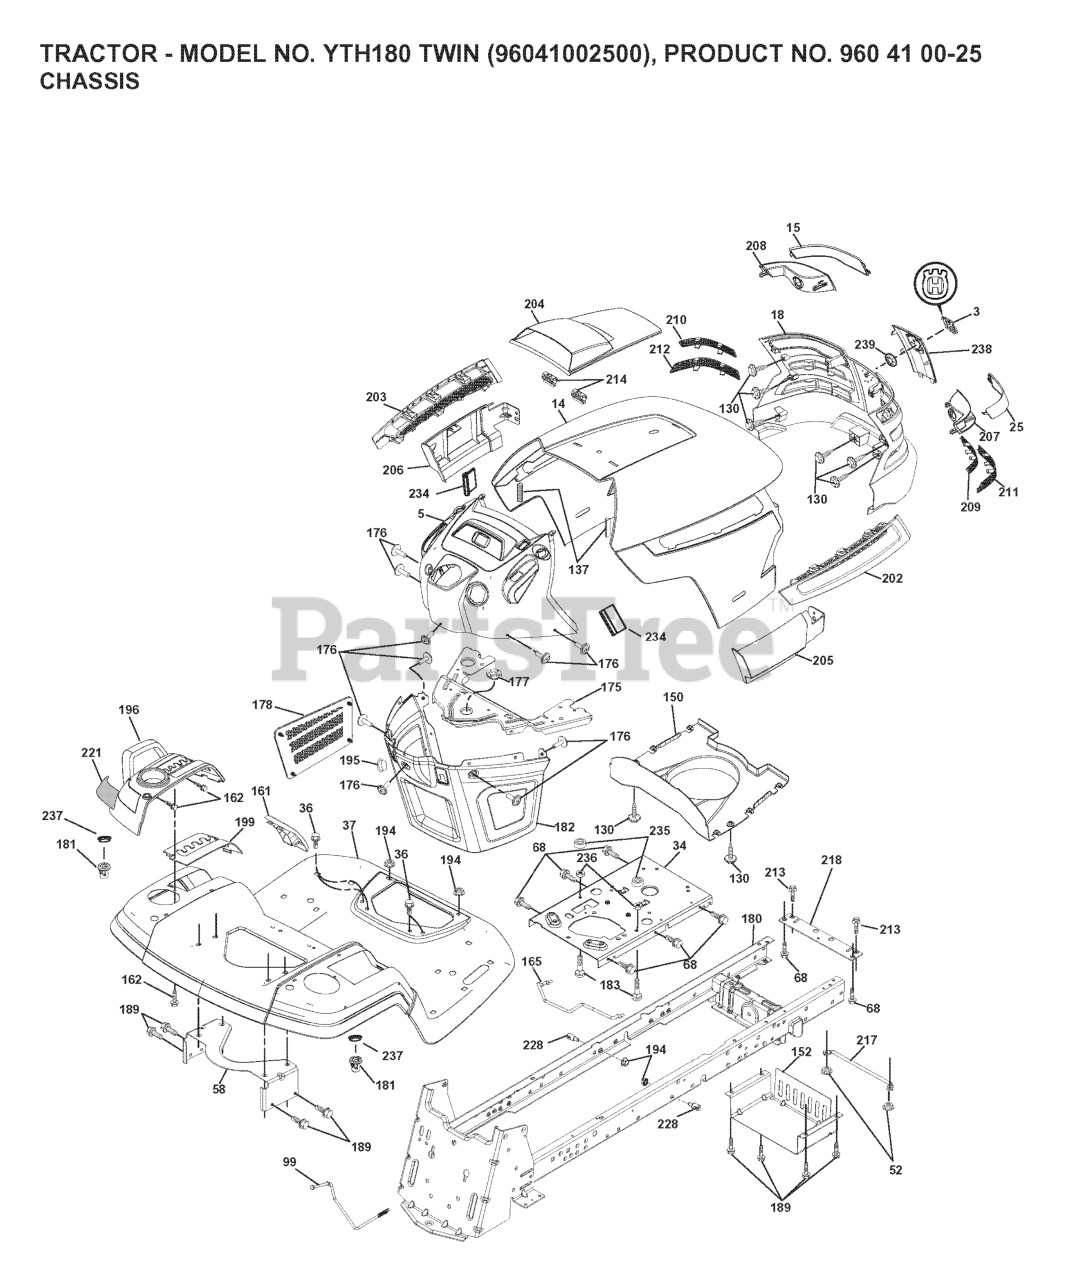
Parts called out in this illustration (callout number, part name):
3	RP LOGO
5	DASH.ASM.HUSQ.GT.E.RECT.W/CK
14	HOOD
15	LENS.LH.TEX.GT.HUSQ.CL
18	GRILL.ASM.HUSQ.TG/CRD.W/TRIM
25	LENS.RH.TEX.GT.HUSQ.CL
34	PLATE.ENGINE.WELDED.CHASSIS
36	SCREW 5/16"
37	FENDER.PNT.TX.GT.CH/FW.ORANGE
52	LOCKNUT
58	BRKT.SUPPORT.FNDR/TANK
68	Screw 5/16-18 x 1/2 Hex, Self Tapping 5/16-18 x 1/2
99	ROD ASM BYPASS
130	SCREW
137	BUMPER DASH
150	AIR.DUCT.TEXGT.HUSQ.SV
152	SHIELD.BROWNING.W/TEX
161	CONSOLE.FUEL.WINDOW.HU
162	SCREW.HI-LO.CONSOLE
165	SUPPORT.TANK.REAR.W/TEX
175	PLATE.CROSSMEMBER.HUSQ
176	SCREW.#10-24X5/8.RN.QU
177	BUSHING, STEERING
178	CARGO.ASM.NET.TXGT.W/C
180	CHASSIS.WLDMT.TX.GT.05
181	BUSHING.MNT.FEND.CRGO.
182	DASH.LOWER.COMMON.12V.
183	BOLT.5/16-18X1-1/4 FULL.THREAD
189	SCREW
194	NUT LOCK HEX FLANGE 5/16-18
195	PLUG.HOLE.DASH.LOWER.12V.BLK
196	RP CONSOLE.ASM.DECKLFT.W/
199	PLATE.DECK.LIFT.HUSQVARNA.GT
202	VENT.SIDE.HOOD.HUSQ.RH.GREY
203	VENT.SIDE.HOOD.HUSQ.LH.GRAY
204	VENT.TOP.HOOD.HUSQVARN
205	SKIRT.HOOD.SIDE.HUSQ.RH.GREY
206	SKIRT.HOOD.SIDE.HUSQ.LH.GREY
207	BEZEL.RH.TEX.GT.HUSQ
208	BEZEL.LH.TEX.GT.HUSQ
209	INSERT.HEX.GRILL.HUSQ.GREY
210	INSERT.HEX.GRILL.HUSQ.
211	INSERT.HEX.GRILL.HUSQ.
212	INSERT.HEX.GRILL.HUSQ.
213	BOLT
214	CLIP.RETAINER.TINNER.
217	ROD PIVOT CHASSIS/HOOD
218	X-PIECE.HOOD.STOP.NON/
221	REFLECTOR.LH.TEX GT HU
228	STUD.FASTNER.W/ANTI-ROTATE
234	BUMPER.HOOD.TEX.HUSQVARNA
235	SPACER FENDER
236	NUT.CENTERLOCK.5/16-
237	PLUG.MOUNT.CARGO.BLK
238	TRIM.HUSQ.TG/CRD.SERVICE
239	NUT PUSH M
